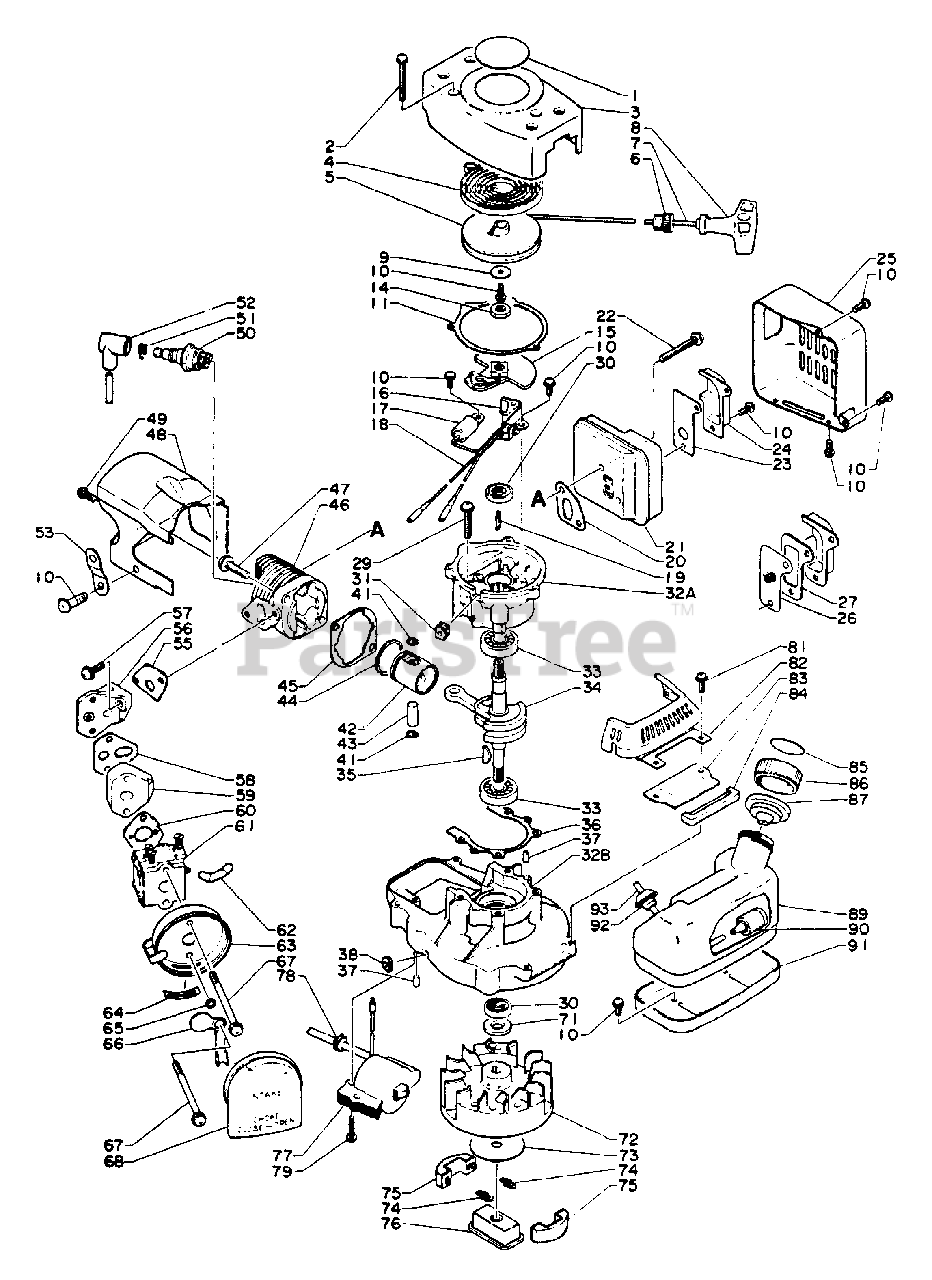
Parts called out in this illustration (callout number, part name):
1	LABEL - ECHO
2	SCREW - 4X40
3	CASE, STARTER
4	SPRING, REWIND
5	REEL, ROPE
6	GUIDE, ROPE
7	ROPE, STARTER - 3X850
8	GRIP, STARTER
10	SCREW - 4X10
11	GASKET, STARTER
15	STARTER PAWL ASSY
16	CONTACT POINT SET
17	CONDENSER
18	LEAD - GROUND
19	PAD, OIL
20	GASKET, EXHAUST
21	CASE, MUFFLER
22	SCREW - 5X40
23	GUIDE, EXHAUST - INNER
24	GUIDE, EXHAUST
25	COVER, EXHAUST
26	SCREEN, SPARK ARRESTOR
27	RETAINER, SCREEN
29	SCREW - 5X30
30	SEAL, OIL
32	CRANKCASE KIT
33	BEARING, BALL - 6200
34	CRANKSHAFT ASSY
36	GASKET, CYLINDER
37	PIN - LOCATING
41	RING, RETAINING
42	PISTON
43	PIN, PISTON
44	RING, PISTON
45	GASKET, CYLINDER
46	CYLINDER
47	SCREW - 6X22
48	COVER, ENGINE
49	SCREW - 5X10
50	SPARK PLUG -- BM-6A
50	SPARK PLUG -- BMR-6A
51	TERMINAL, SPARK PLUG CAP
52	CAP, SPARK PLUG
53	BRACKET
55	GASKET, INTAKE
56	BASE, INSULATOR
57	SCREW - 5X16
58	GASKET, INTAKE
59	INSULATOR, INTAKE
60	GASKET, INTAKE
61	CARBURETOR WA-89
62	PIPE
63	CASE, AIR FILTER
64	GROMMET
65	WASHER - 5
66	SHUTTER, CHOKE
67	SCREW - 5X57
68	FILTER, AIR
72	FLYWHEEL
73	PLATE, CLUTCH
74	SPRING, CLUTCH
75	SHOE, CLUTCH
76	HUB, CLUTCH
77	COIL, IGNITION
79	SCREW - 4X20
81	SCREW - 4X12
83	BRACKET, FUEL TANK
84	CUSHION
85	LABEL - FUEL MIX
86	CAP
87	VENT
89	TANK, FUEL
90	FILTER, FUEL
91	BRACKET, FUEL TANK
93	PIPE, FUEL - CORRUGATED
